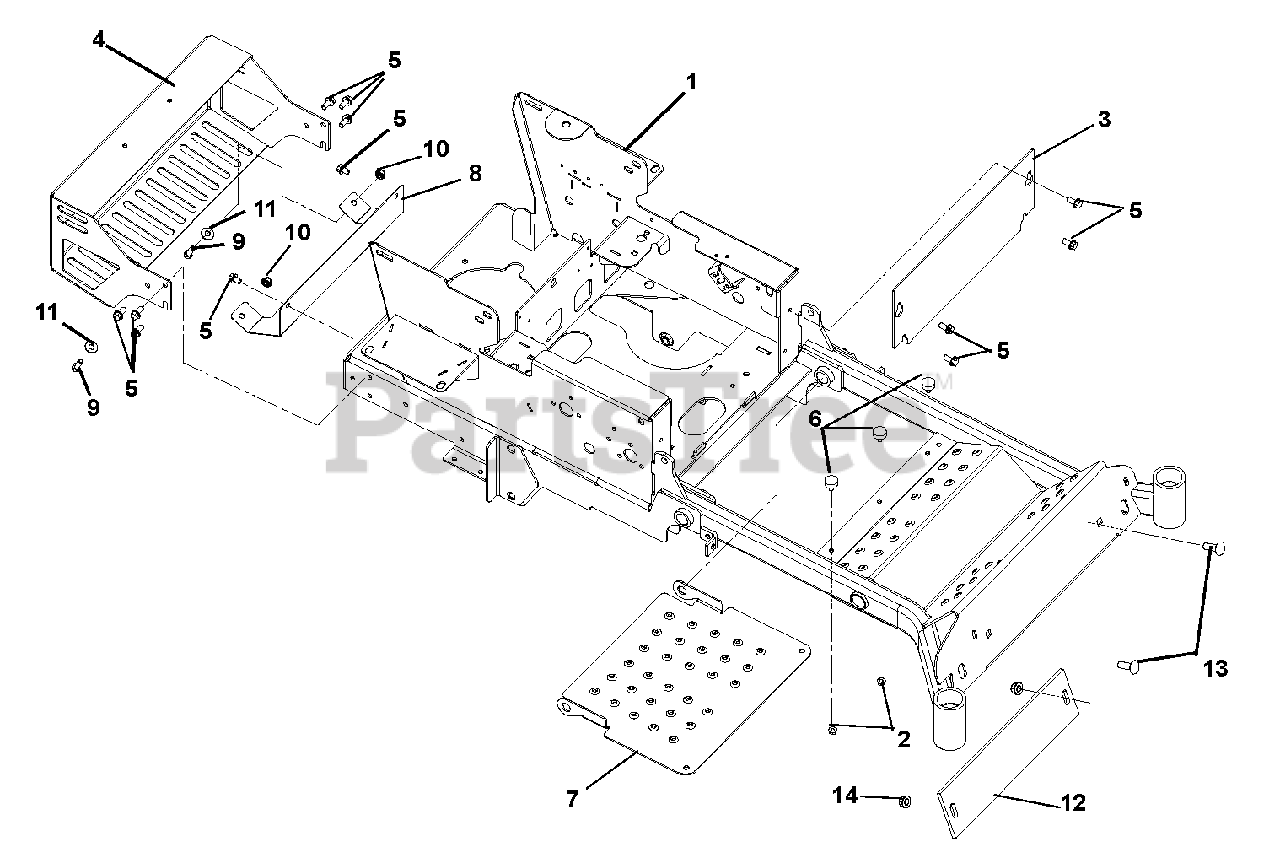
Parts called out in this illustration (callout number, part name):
1	ZT Head 44-48 Main Frame Weldment (SN# 000200 - 000799)
2	Nut, Spin Lock Flange .312-18
3	Kick Plate
4	Weldment Gravely, CZ Bumper
5	Screw, Tapping .38-16 x .75 Hex Washer Head
6	Bumper, Rubber
7	Panel, Inspection
8	Heat Shield, Compact Z
9	Bolt, Hex .38-16 x 1.00 Grade 5
10	Nut, Nyloc Flange .38-16
11	Washer, Flat Steel .438 x 1.00 x .083
12	Counterwieght CZ Front- Red
13	Bolt, Round Head Square Neck .50-13 x 1.50 Grade 5
14	Nut .50-13 Nyloc Flange
